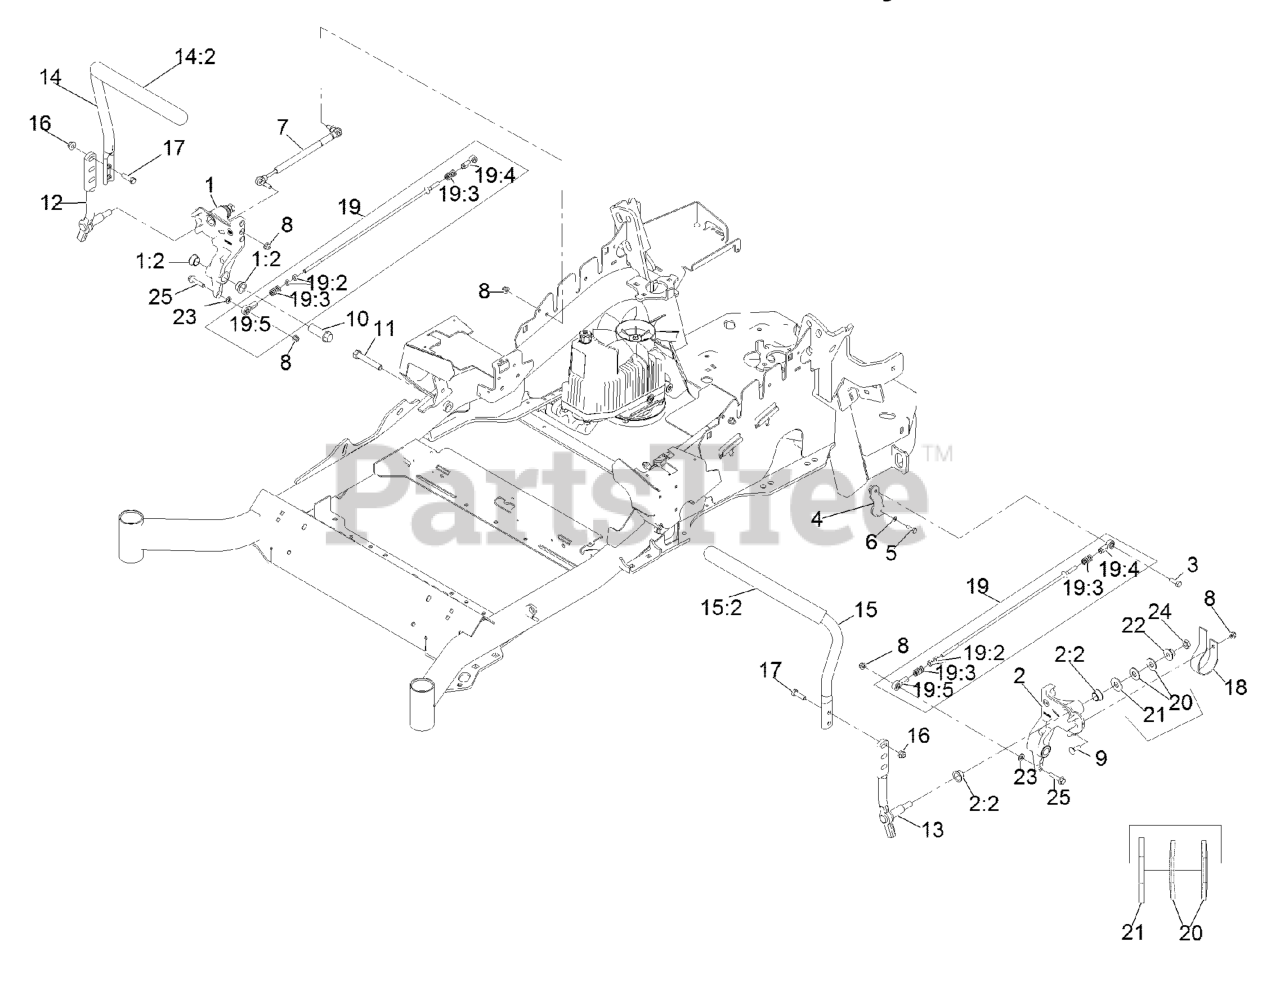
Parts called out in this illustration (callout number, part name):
1	RH MOTION CONTROL AND BUSHING ASM
1:2	BUSHING-FLANGE
2	LH MOTION CONTROL AND BUSHING ASM
2:2	BUSHING-FLANGE
3	SCREW-HH, THREAD LOCKING
4	ARM-CONTROL, PUMP
5	SCREW-HH
6	WASHER-SPRING
7	DAMPER-CONTROL, MOTION
8	NUT-HF, NI
9	BOLT-CARR
10	HUB-THREADED
11	SCREW-HH
12	LEVER-CONTROL MOTION, RH
13	LEVER-CONTROL MOTION, LH
14	RH STEERING HANDLE ASM
14:2	GRIP-LEVER, CONTROL
15	LH STEERING HANDLE ASM
15:2	GRIP-LEVER, CONTROL
16	NUT-HF, NI
17	SCREW-HH
18	SPRING-LEAF
19	PUMP LINKAGE REAR ASM
19:2	NUT-HEX
19:3	SPRING-COMPRESSION
19:4	BALLJOINT-LH
19:5	BALLJOINT-RH
20	WASHER-SPRING
21	WASHER-FLAT
23	WASHER-PLAIN
24	NUT-JAM
25	SCREW-HHF
